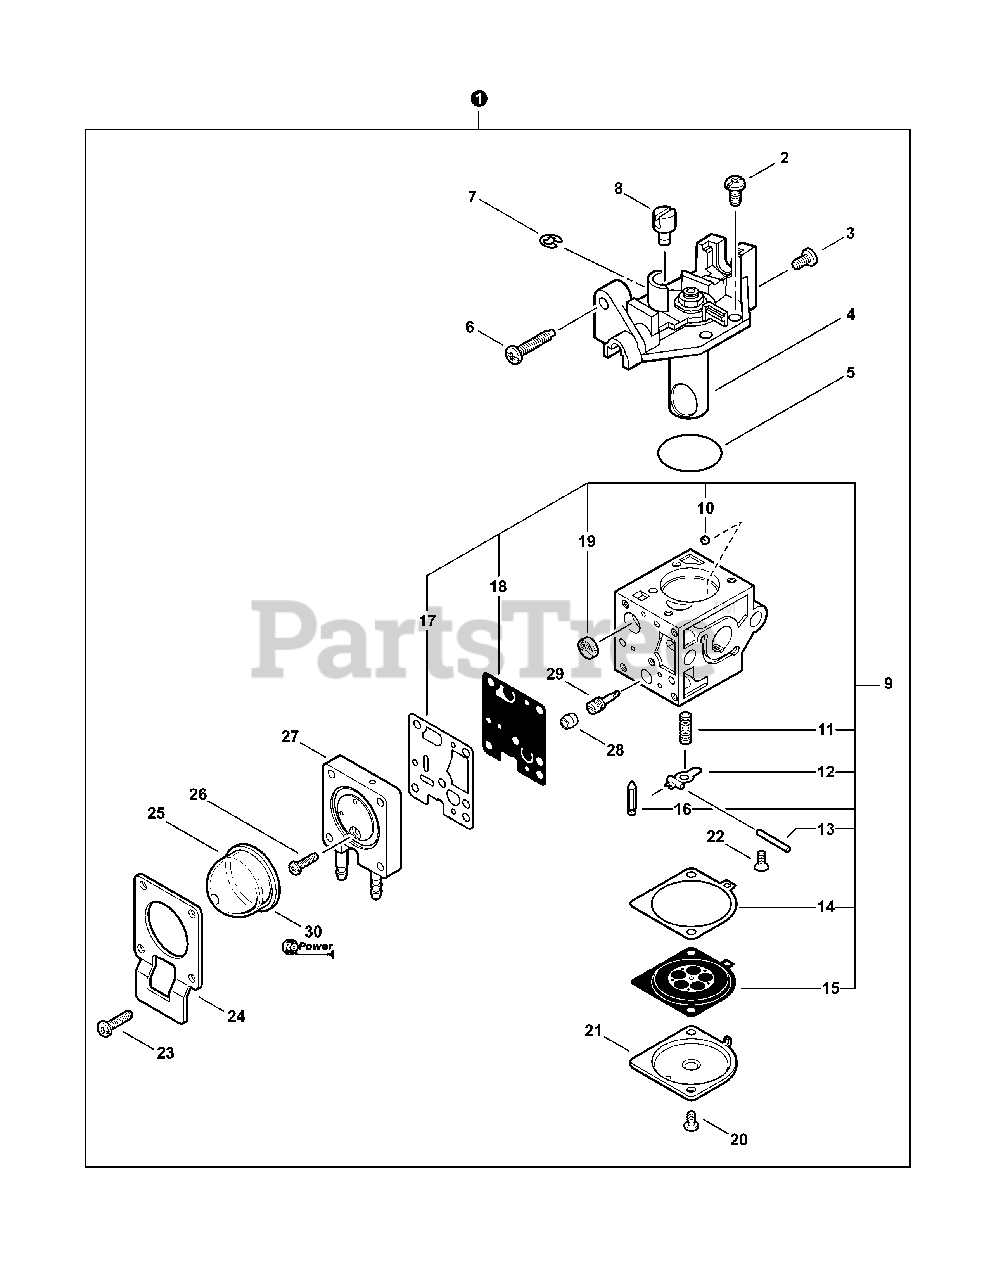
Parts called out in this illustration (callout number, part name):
1	CARBURETOR - RB-K93
4	COVER ASSY, ROTOR
6	SCREW, IDLE ADJUST
9	REPAIR KIT
10	GUIDE, ROLLER
11	SPRING, METERING LEVER
12	LEVER, METERING
13	PIN, METERING LEVER
14	GASKET, DIAPHRAGM
15	DIAPHRAGM, METERING
16	VALVE, INLET NEEDLE
17	GASKET, PUMP
18	DIAPHRAGM, PUMP
19	STRAINER
21	COVER, METERING DIAPHRAGM
24	RETAINER, PURGE BULB
25	BULB, PURGE
27	BODY ASSY, PURGE
29	NEEDLE, HIGH SPEED
30	FUEL SYSTEM KIT
